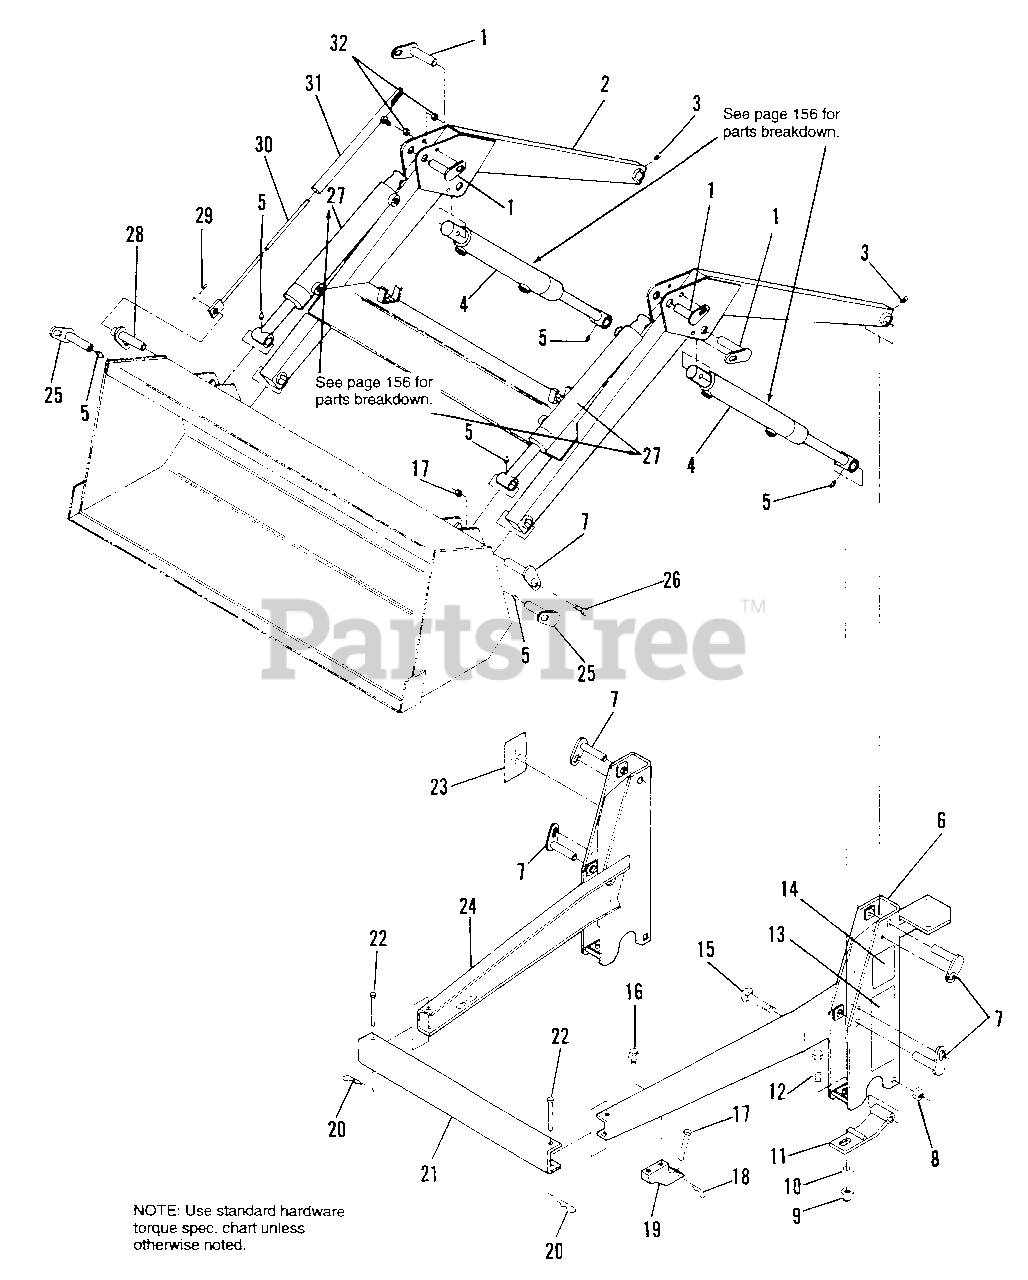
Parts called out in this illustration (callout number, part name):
1	PIN ASSY., 3/4 x 2-1/2 (Cyl. Base)
2	FRAME, Lift Boom
3	FITTING, Grease, 1/4-28
4	Cylinder, Lift (Code HG)
5	GREASE FITTING, 1/4-28
6	FRAME, Left Side
7	PIN ASSY., 3/4 x 3-1/4 (Frame, L.H.)
8	LOCKNUT, 5/8-11
9	LOCKNUT, Elastic, 5/8-11
10	WASHER, Flat, 5/8
12	CAPSCREW, 5/8-11 x 3"
13	DECAL, Danger
14	DECAL, Caution
15	CARRIAGE BOLT, 5/8-11 x 3-3/4, Gr. 5
16	CAPSCREW, Serrated Hd., 1/2-13 x 3/4
17	PIN, Clevis, 5/8 x 3-1/4
18	PIN, Hair Cotter, 3/32 x 2-11/16
19	HOOK, Side Frame Mounting
20	PIN, Hair Cotter, 3/32 x 1-7/8
21	BUMPER, Front
22	PIN, Clevis, 3/8 x 4
23	DECAL, Caution
24	FRAME, Right Side
25	PIN ASSY., 3/4 x 3-1/4 (Bucket)
26	BOLT, Shoulder 3/8 x 1
27	Cylinder, Bucket, (Code HF)
28	PIN ASSY., 3/4 x 3-1/4
29	COTTER PIN, 5/32 x 1-1/2
30	ROD, Indicator
31	TUBE, Indicator Guide
32	LOCKNUT, 3/8-16
